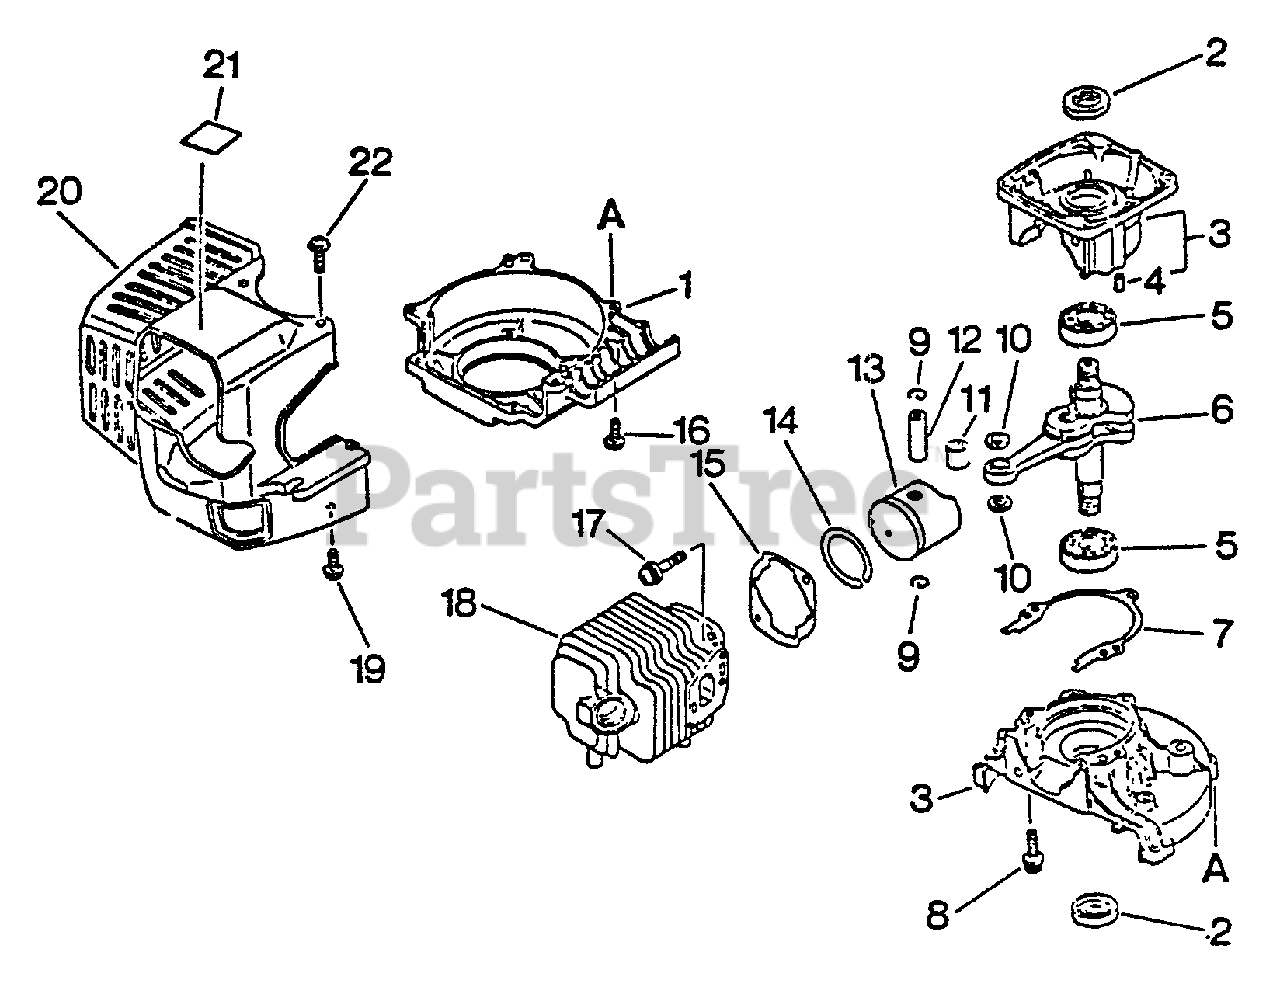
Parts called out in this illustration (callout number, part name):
1	COVER, FAN
2	SEAL, OIL 12
3	CRANKCASE KIT
4	PIN, LOCATING 4
5	BEARING, BALL - 6201 C3
6	CRANKSHAFT ASSY
7	GASKET, CRANKCASE
8	SCREW 5×28
9	RING, SNAP
10	WASHER, THRUST
11	BEARING, NEEDLE
12	PIN, PISTON 8
13	PISTON
14	RING, PISTON
15	GASKET, CYLINDER
16	SCREW 4×14
17	BOLT 5×22
19	SCREW 4×16
20	COVER, ENGINE - ORANGE
20	COVER, ENGINE - GRAY
21	LABEL, MODEL
22	SCREW 4×12
